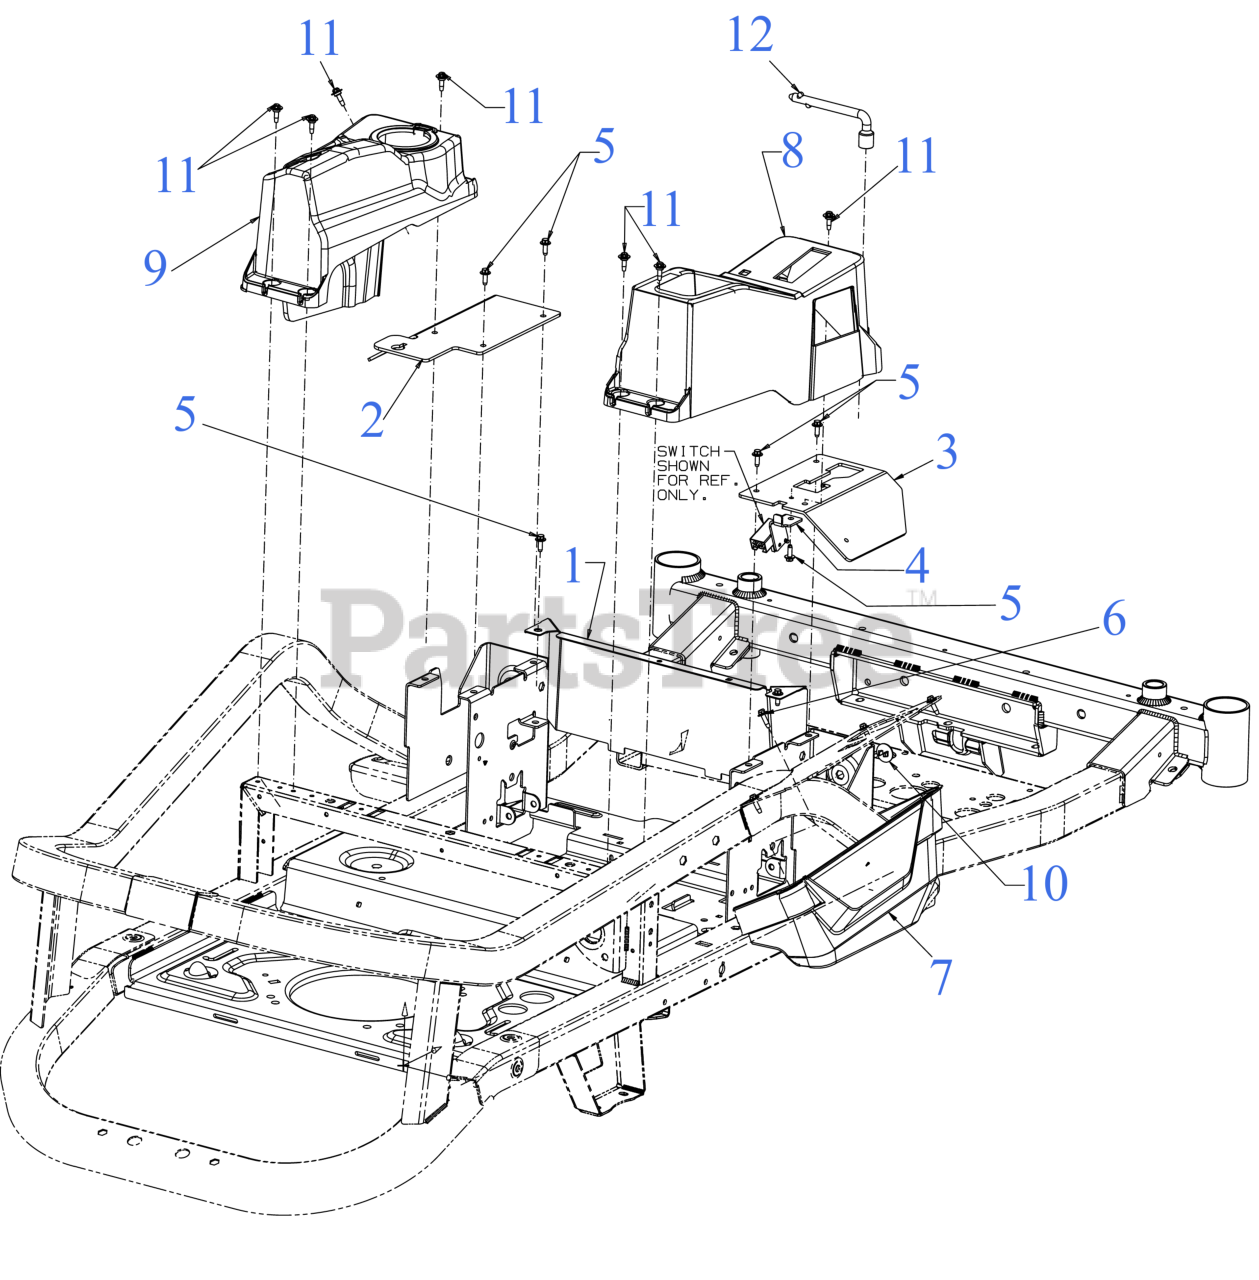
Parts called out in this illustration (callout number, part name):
1	SEAT BOX FRONT PLATE
2	CONTROL BRACKET (LH)
3	CONTROL BRACKET (RH)
4	SWITCH MOUNTING BRACKET
5	SCREW M6-1 x .625
6	SCREW 1/4-10 x .750
7	CONTROL PANEL CONSOLE
8	CONSOLE (RH)
9	CONSOLE (LH)
10	HOLE PLUG 1.0 OD
11	SHOULDER SCREW M6-1 .368 X.115
12	MULTI TOOL 1/2" SOCKET
